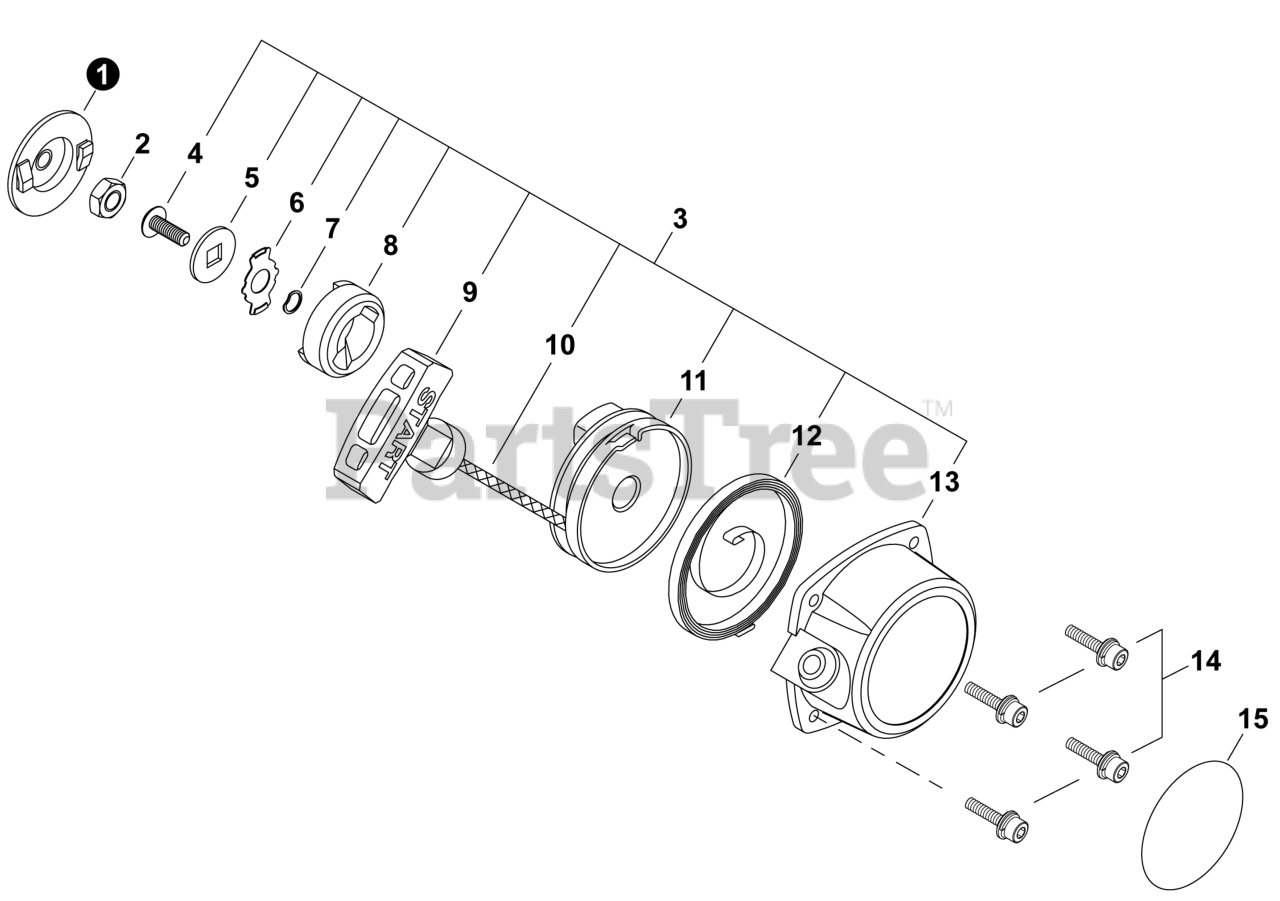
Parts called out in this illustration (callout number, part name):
1	PULLEY, STARTER
2	NUT M8×1
3	STARTER ASSY, RECOIL
4	SCREW 5
6	RETAINER
7	WASHER, WAVE
8	PLATE, CAM
9	GRIP, STARTER
11	REEL, ROPE
12	SPRING, RECOIL
13	CASE, RECOIL STARTER
14	BOLT, ADHESIVE M4×12
15	LABEL - RECOIL STARTER
